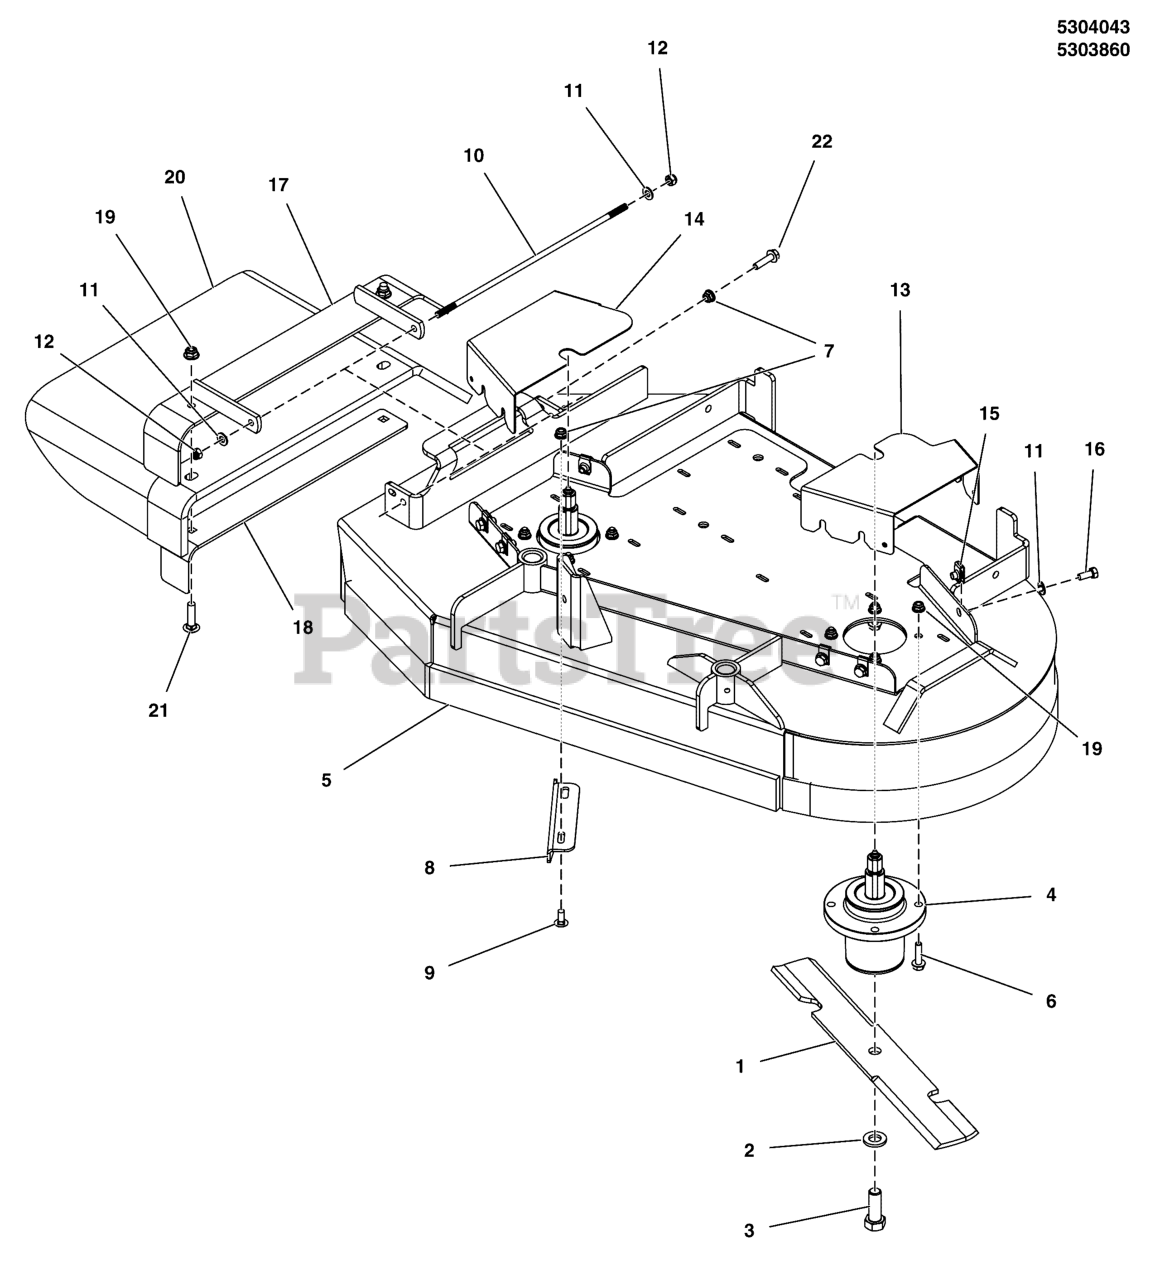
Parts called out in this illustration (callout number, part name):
1	BLADE SET, 36 DECK (2)
2	WASHER, BLADE BOLT, 9/16" F436, CZ
3	BOLT, 5/8-11 X 1-3/4 GD8
4	SPINDLE, ASSM, ALUMINUM - 5.25
5	DECK SHELL W/ DECALS, 36, SW25
6	BOLT, 3/8-16 X 1-1/4, FLANGE, GD 5, CZ
7	NUT, 5/16-18 HEX NYLOCK FLANGE NUT
8	PLATE, DEFLECTOR, SWFW25 36" - BLK
9	BOLT, 5/16-18 X 3/4, CARRIAGE, GD5, CZ
10	ROD, 5/16 X 13.75, TBE, CZ
11	WASHER, 5/16" SAE
12	NUT, 5/16-24 HEX NYLON LOCK
13	GUARD, DECK, SW25 36" LH - RED
14	GUARD, DECK, SW25 36" RH - RED
15	BODY CLIP, 5/16-18-7GA MATERIAL
16	BOLT, 5/16-18 X 3/4 GD5
17	WELD, MOUNT, DISCHARGE CHUTE - BLK
18	SUPPORT, DISCHARGE CHUTE - BLK
19	NUT, 3/8 - 16 HEX NYLOCK FLANGE
20	CHUTE, RUBBER DISCHARGE CHUTE (5104441)
21	BOLT, 3/8-16 X 1-1/2, CARRIAGE, GD5, CZ
22	BOLT, 5/16-18 X 3/4 GD5
